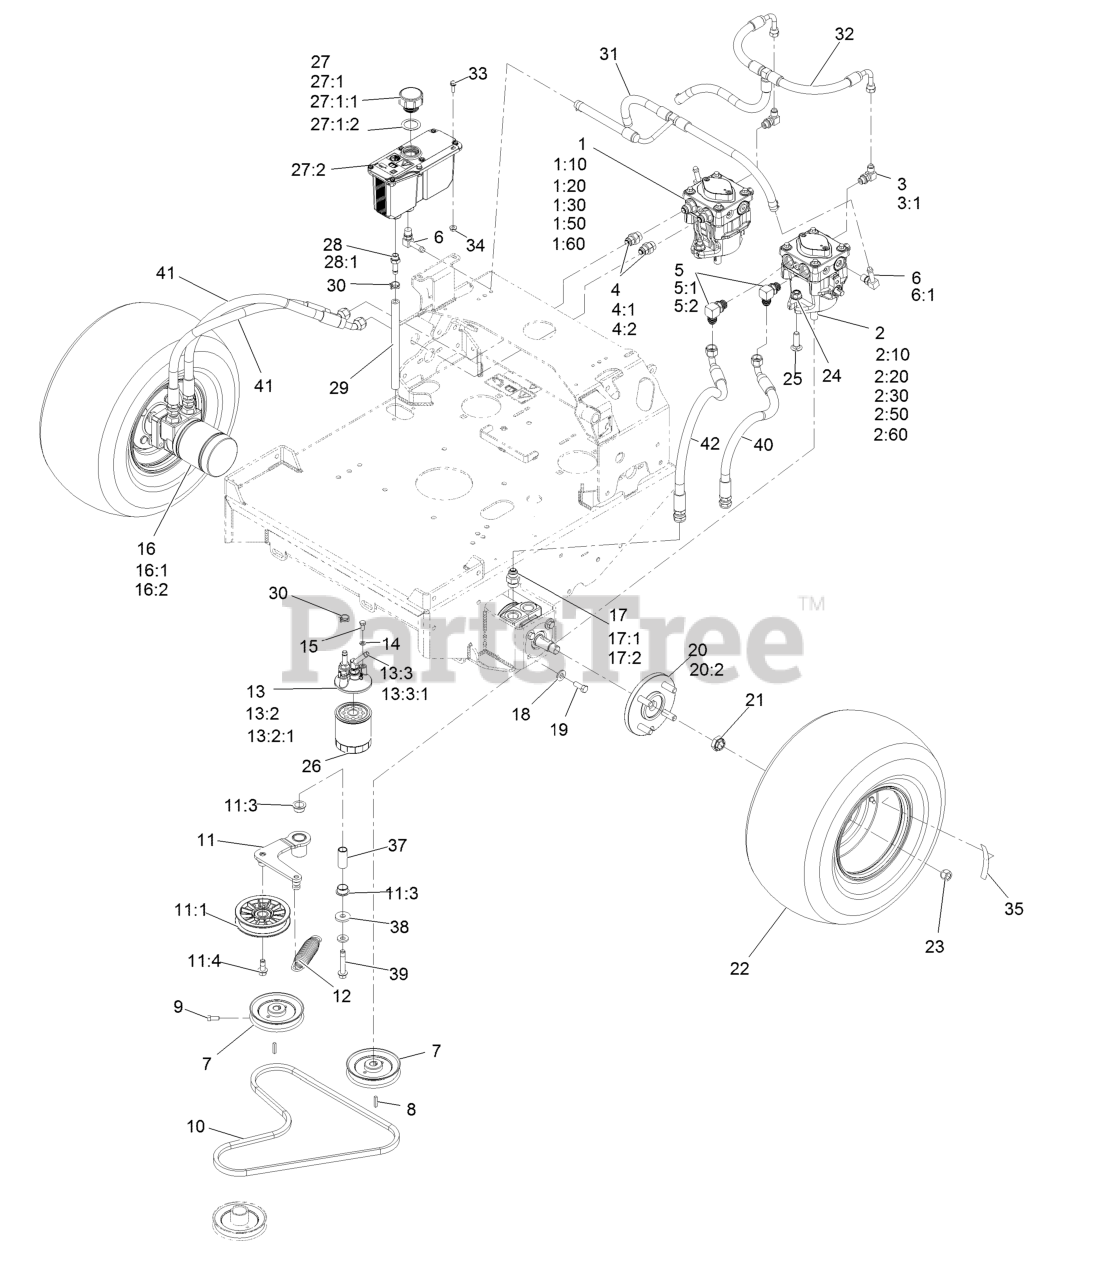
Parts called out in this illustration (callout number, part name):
1	Pump-HYD Pe RH TTH
1:10	Input Shaft Kit
1:20	Bearing-Thrust
1:30	Cylinder Block Kit
1:50	Seal Overhaul Kit
1:60	Kit, 10Cc Pump Kit
2	Pump-HYD Pe LH TTH
2:10	Input Shaft Kit
2:20	Bearing-Thrust
2:30	Cylinder Block Kit
2:50	Seal Overhaul Kit
2:60	Kit, 10Cc Pump Kit
3	Fitting-Elbow, 90 DEG
3:1	O-Ring
4	Adapter-Straight
4:1	O-Ring-SAE #8
4:2	O-Ring-37 Flare #8
5	Elbow-90deg
5:1	O-Ring-SAE #8
5:2	O-Ring-37 Flare #8
6	Fitting-Elbow, 90
6:1	O-Ring
7	Sheave ASM
8	Key-5Mm X 5Mm X 25Mm
9	Screw-Set, SQH 5/16-18 X 3/4
10	Belt
11	ASM, Pump Idler
11:1	Pulley-Idler, Flat
11:3	Bushing-Flanged
11:4	Screw-Hfh
12	Spring-Extension
13	ASM, Filter Head
13:2	Adapter-Straight
13:2:1	O-Ring
13:3	Fitting-Barbed, 45 DEG
13:3:1	O-Ring
14	Washer-Lock 1/4 Heavy
15	Screw-HH 1/4-20 X 5/8
16	HYD Motor ASM
16:1	Seal Kit
16:2	Bearing And Seal Kit
17	Adapter-Straight
17:1	O-Ring
17:2	O-Ring-37 Flare #8
18	Washer-Spring Disc 3/8
19	Screw-HH 3/8-16 X 1
20	Wheel Hub ASM
20:2	Stud-Wheel
21	Nut-Lock
22	Tire And Wheel Assy
23	Nut-Lug 1/2-20
24	Nut-HF, NI
25	Bolt-Carriage 7/16-14 X 1 1/2
26	Element, Oil Filter
27	ASM, HYD Reservoir
27:1	Reservoir-HYD
27:1:1	Cap-Reservoir, HYD
27:1:2	Gasket-Cap
27:2	Decal-Warning
28	Adapter-Straight
29	Hose-Charge
30	Clamp-Hose 11/16
31	Hose, Case
32	Hose, Charge
33	Screw-Machine 1/4-20 X 3/4
34	Nut-Whizlock 1/4-20
35	Decal-Torque Wheel Lug-Hub
37	Pivot, Idler
39	Screw-HHF W/ Patch
40	ASM, HP Hose
41	Hose,Hydraulic W/Cover
42	HYD Hose ASM
